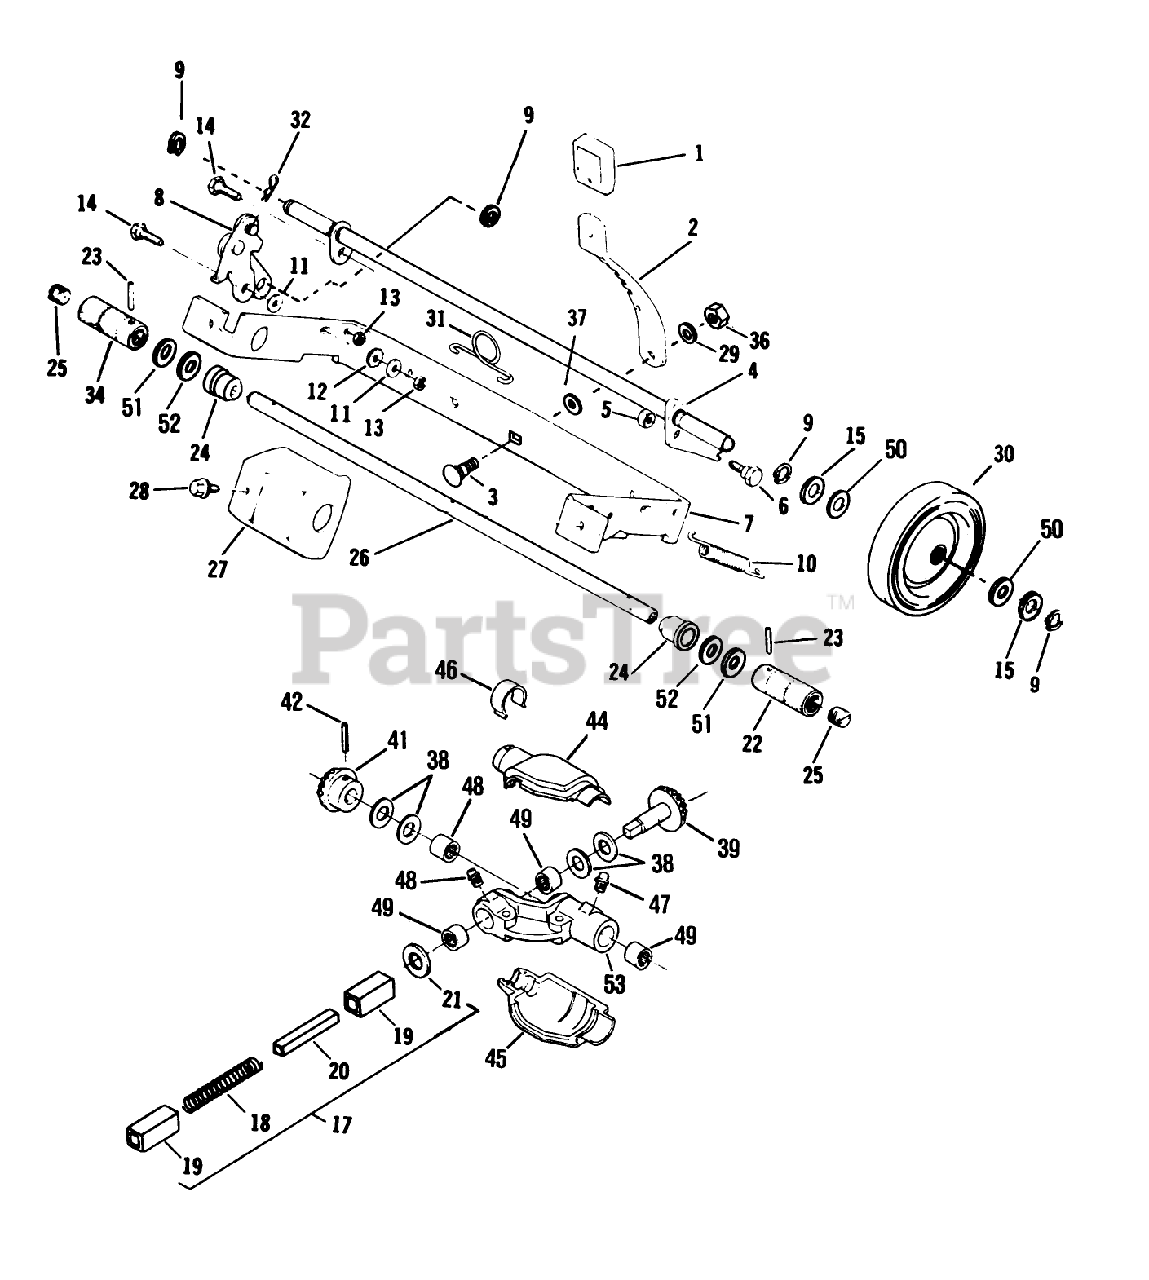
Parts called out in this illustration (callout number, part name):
2	LEVER
4	AXLE & TORQUE LUG ASM
5	LOCKNUT E
6	BOLT RB&W
7	BRACKET *GREEN
8	CLUTCH AY ARGO
9	RET RING
10	SPRING
11	WASHER S
13	STOP NUT
14	BOLT RB&W
15	SPACER
18	SPRING
19	BUSHING BKWY
21	THRUST WASHER
22	ROLLER-LEFT
24	SLEEVE &BEARING AY
25	GREASE PLUG
26	DRIVE SHAFT & TAG
29	WASHER S
31	SPRING N.A.S
33	RET RING
36	LOCKNUT E
37	WASHER SPRING LAR
38	THRUST WASHER
39	GEAR BEST
41	GEAR ADVANCE
42	ROLL PIN
44	GEAR COVER UPPER
47	**FITTING LINCOLN
50	WASHER
52	THRUST WASHER
